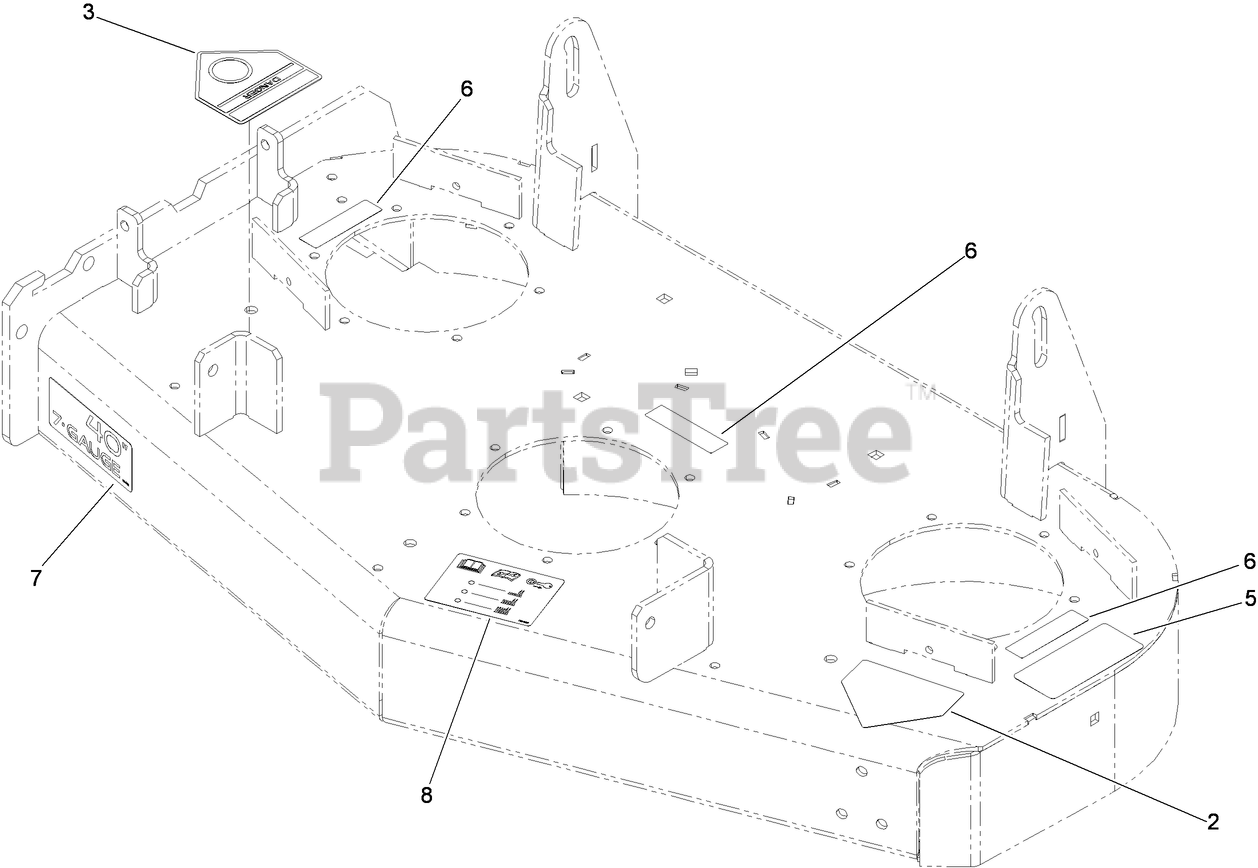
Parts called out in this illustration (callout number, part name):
2	DECAL-DANGER
3	DECAL-DANGER
5	DECAL-TORQUE
6	DECAL-COVER, MISSING
8	DECAL-SCALP, ANTI
